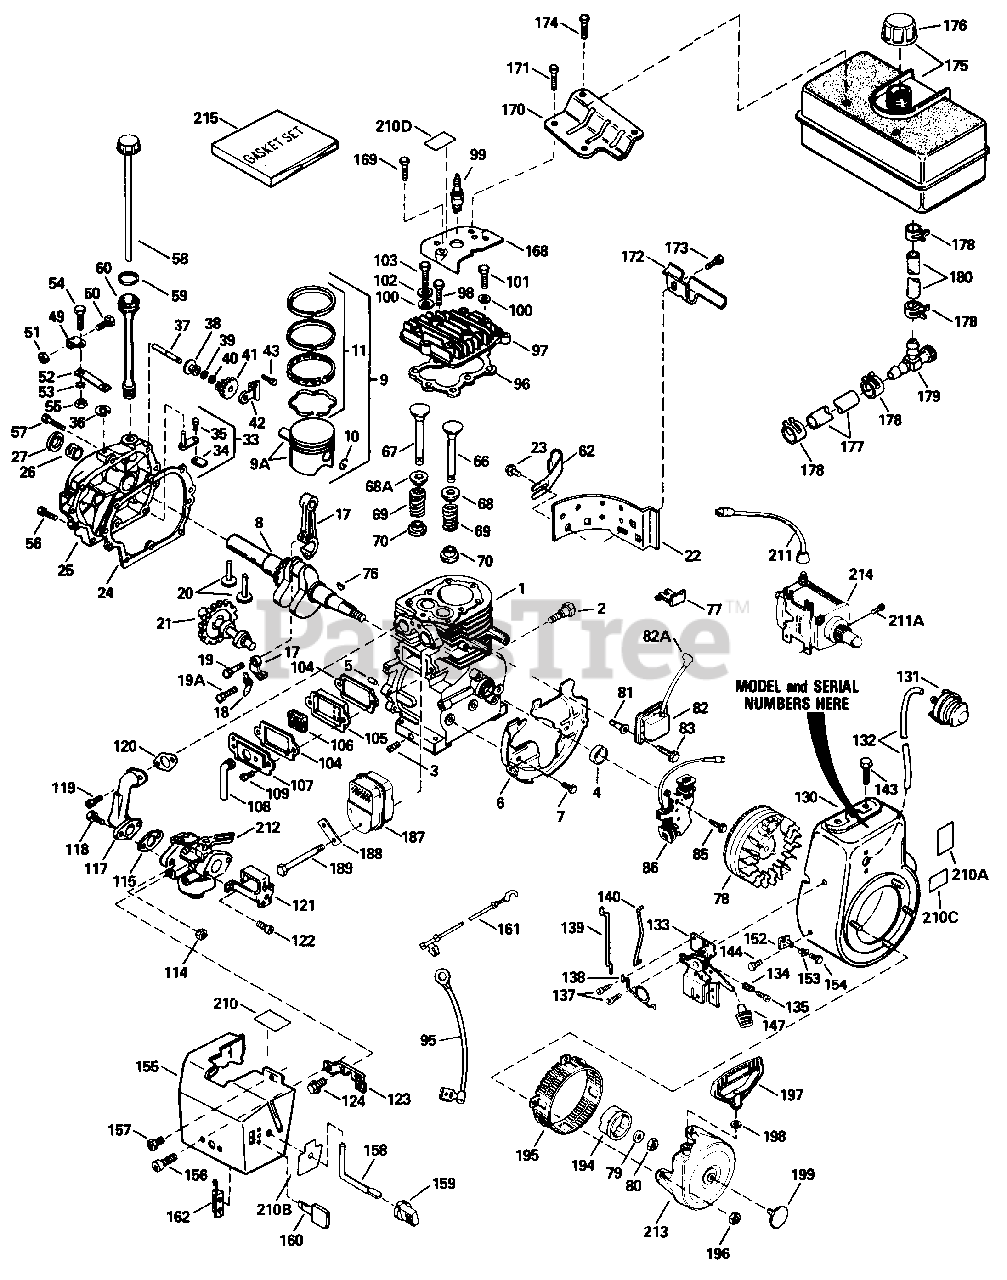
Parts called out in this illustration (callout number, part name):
1	Cylinder
2	Screw, Hex Hd. Shoulder, 1/4-20 x 1/2
3	Plug, Pipe
4	Seal, Oil
5	Pin, Dowel
6	Baffle, Blower Housing
7	Screw, Hex Washer Hd. Durlok, 1/420 x 5/8
8	Crankshaft
9	Piston, Pin & Ring Ass'y.
9A	Piston & Pin Ass'y.
10	Ring, Piston Pin Retaining
11	Ring Set, Piston
17	Rod Ass'y., Connecting
18	Dipper, Oil
19	Bolt, Connecting Rod
19A	Bolt, Connecting Rod
20	Lifter, Valve
21	Camshaft
22	Extension, Blower Housing
23	Screw, Hex Hd. Sems, 10-24 x 1/2
24	Gasket, Cylinder Cover
25	Cover Ass'y., Cylinder
26	Bushing, Crankshaft
27	Seal, Oil
33	Rod Ass'y., Governor
34	Yoke, Governor
35	Screw, Fil. Hd. Sems, 6-40 x 5/16
36	Ring, Retaining
37	Shaft, Governor
38	Spool, Governor
39	Washer, Flat
40	Ring, Retaining
41	Gear, Governor
42	Bracket, Governor Gear
43	Screw, Hex Washer Hd. Thread Forming, 10-24 x 1/2
49	Clamp, Governor Lever
50	Screw, Hex Washer Hd., 10-32 x 3/4
51	Lock Nut, Hex "Keps," 10-32
52	Lever, Governor
53	Washer, E.T. Lock
54	Screw, Hex Washer Hd., 8-32 x 5/16
55	Lock Nut, Hex "Keps," 8-32
56	Screw, Hex Washer Hd. Powerlok, 1/4-20 x 1-11/16
57	Screw, Hex Washer Hd. Powerlok, 1/4-20 x 1-3/16
58	Dipstick, Oil
60	Tube, Oil Fill
62	Clip, Fill Tube
66	Valve, Exhaust
67	Valve, Intake
68	Cap, Upper Valve Spring
68A	Seai Ass'y., Intake Valve
69	Spring, Valve
70	Cap, Lower Valve Spring
76	Key, Flywheel
77	Clip, Spring
78	Flywheel
79	Washer, Lock
80	Nut, Flywheel
81	Stud, Solid State Mounting
82	Solid, State Ass'y.
82A	Cover, Spark Plug
83	Screw, Hex Hd. Sems, 10-24 x 1
85	Screw, Hex Hd. Sems, 1/4-20 x 3/4
86	Coil Ass'y., Alternator (18 Watt)
95	Wire, Ground
96	Gasket, Cylinder Head
97	Head, Cylinder
98	Screw, Hex Flange Hd., 5/16-18 x 1-1/2
99	Spark Plug
100	Washer, Flat
101	Screw, Special Hex Hd. Tapped, 5/16-18 x 1-3/4
102	Washer, Belleville
103	Screw, Hex Flanged Hd., 5/16-18 x 2
104	Gasket, Breather
105	Body, Breather
106	Element, Breather
107	Cover, Breather
108	Tube, Breather
109	Screw, Hex Hd. Sems, 10-24 x 1/2
114	Nut & Lock Washer, 1/4-28
115	Gasket, Carburetor
117	Pipe, Intake
118	Screw, Fil. Hd. Sems, 1/4-28 x 1
119	Screw, Torx Fil. Hd. Sems, 5/16-18 x 1-1/8
120	Gasket, Intake Pipe
121	Bracket, Choke
122	Screw Fil. Hd. Sems, 10-32 x 1/2
123	Bracket, Carburetor Cover Mounting
124	Screw, Hex Washer Hd. Sems, Taptite, 8-36 x 5/8
130	Housing, Blower
131	Primer Ass'y.
132	Line, Primer
133	Bracket Ass'y., Control
134	Spring, Compression
135	Screw, Fil. Hd., 5-40 x 7/16
137	Screw, Hex Washer Hd. Thread Cutting, 10-32 x 1/2
138	Spring, Speed Control
139	Link, Governor
140	Link, Governor-to-Throttle
143	Screw, Hex Hd. Spinlock Thread Forming, 5/16-18 x 3/4
144	Screw, Phil. Hex Hd. Sems, 5/16-24 x 21/32
147	Knob, Control
152	Bracket, Grommet Mounting
153	Grommet, Plastic
154	Screw, Pan Hd. Taptite, 8-32 x 3/8
155	Cover, Carburetor
156	Screw, Hex Washer Hd. Sems, 10-32 x 3/8
157	Screw, Hex Washer Hd. Self- Drilling, 10-32 x 1/2
158	Rod, Choke
159	Knob, Choke
160	Key, Ignition
161	Wire, Ground
162	Terminal Ass'y.
168	Cover, Cylinder Head
169	Screw, Hex Washer Hd. Taptite, 1/4-20 x 5/8
170	Plate, Fuel Tank Mounting
171	Screw, Hex Hd., 5/16-18 x 5/8
172	Bracket, Fuel Tank
173	Screw, Hex Washer Hd. Durlok, 1/4-20 x 5/8
174	Screw, Hex Washer Hd. Thread Cutting, 1/4-15 x 7/8
175	Tank, Fuel
176	Cap, Fuel Tank
177	Line, Fuel
178	Clamp, Fuel Line
179	Valve, Fuel Shut-Off
180	Line, Fuel
188	Plate, Lock
189	Screw, Flanged Hex Hd., 5/16-18 x 4-3/16
194	Hub, Starter
195	Screen, Starter
196	Nut & Lock Washer, 1/4-28
197	Starter Handle, Mitten Grip
198	Washer, Flat
199	Plug, Starter
210	Decal, Instruction
210A	Decal, Name
210B	Decal, Choke
210C	Decal, Primer
210D	Decal, Writing (Bilingual)
211	Cord, Extension
211A	Screw, Hex Washer Hd. Sems, 1/4-20 x 1/2
212	Carburetor
213	Starter, Rewind
214	Motor Kit, Electric Starter (120 Volt)
215	Gasket Set
